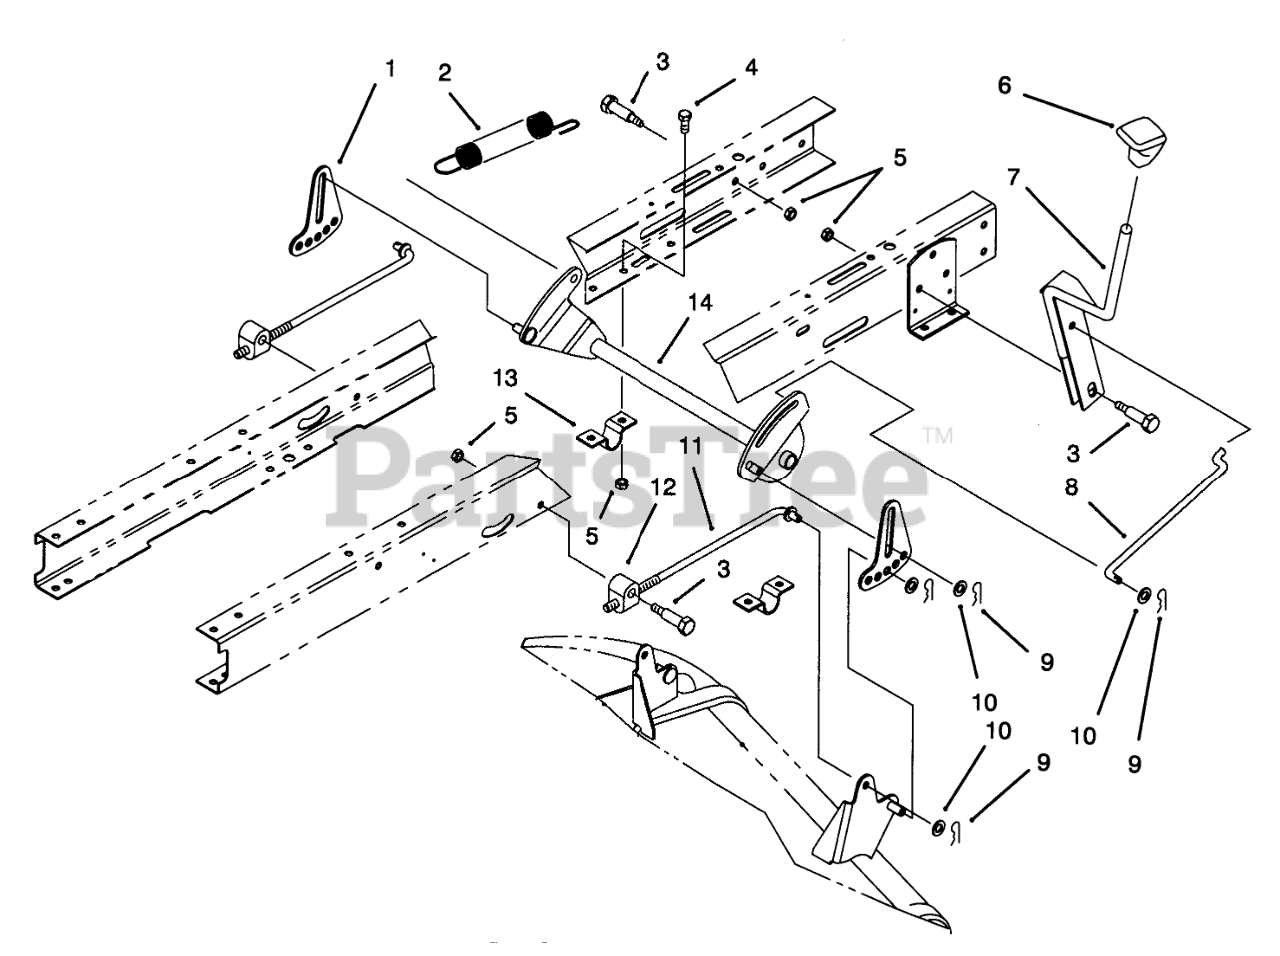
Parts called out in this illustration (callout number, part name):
1	Link-Adjusting H.O.C
2	SPRING-EXTENSION
3	SCREW-SHOULDER, HH
4	SCREW-HH
5	NUT-LOCK, NI
6	SHIFT KNOB
7	Lever-H.O.C.
8	LINK-HOC
9	PIN-COTTER
10	WASHER-FLAT
11	ROD-HANGER, REAR
12	TRUNNION-HOC
13	CLAMP-PIVOT, HOC
14	Pivot-H.O.C.
